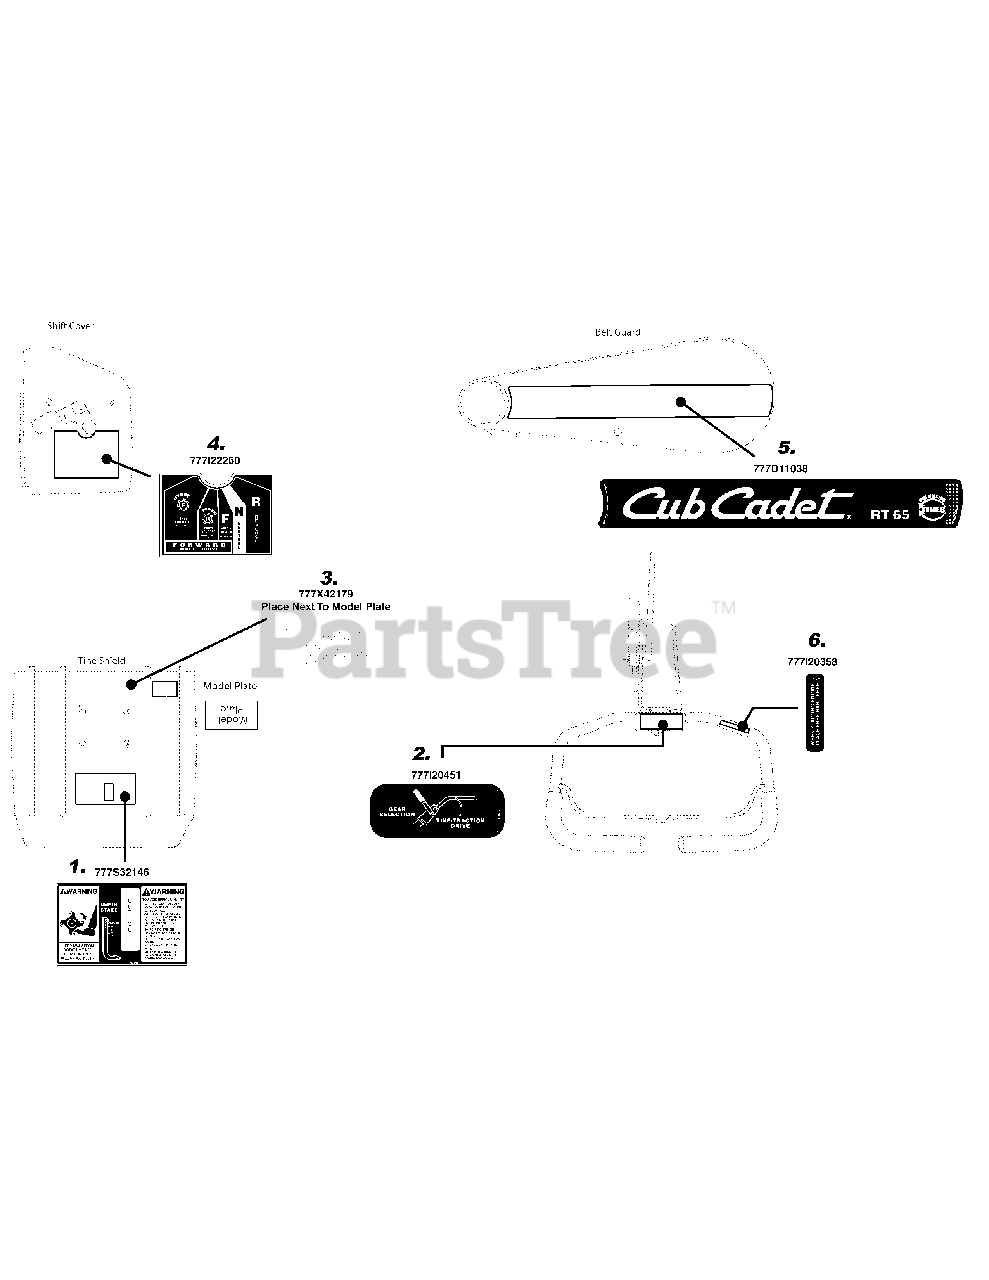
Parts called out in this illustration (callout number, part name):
1	LABEL-TINE SHIELD
2	LABEL-GEAR/TRACTIO
3	LABEL-CUB HOTLINE
4	LABEL-SHIFT P0SITION
5	LABEL-BELT GUARD
6	LABEL-PLACE HAND HERE
